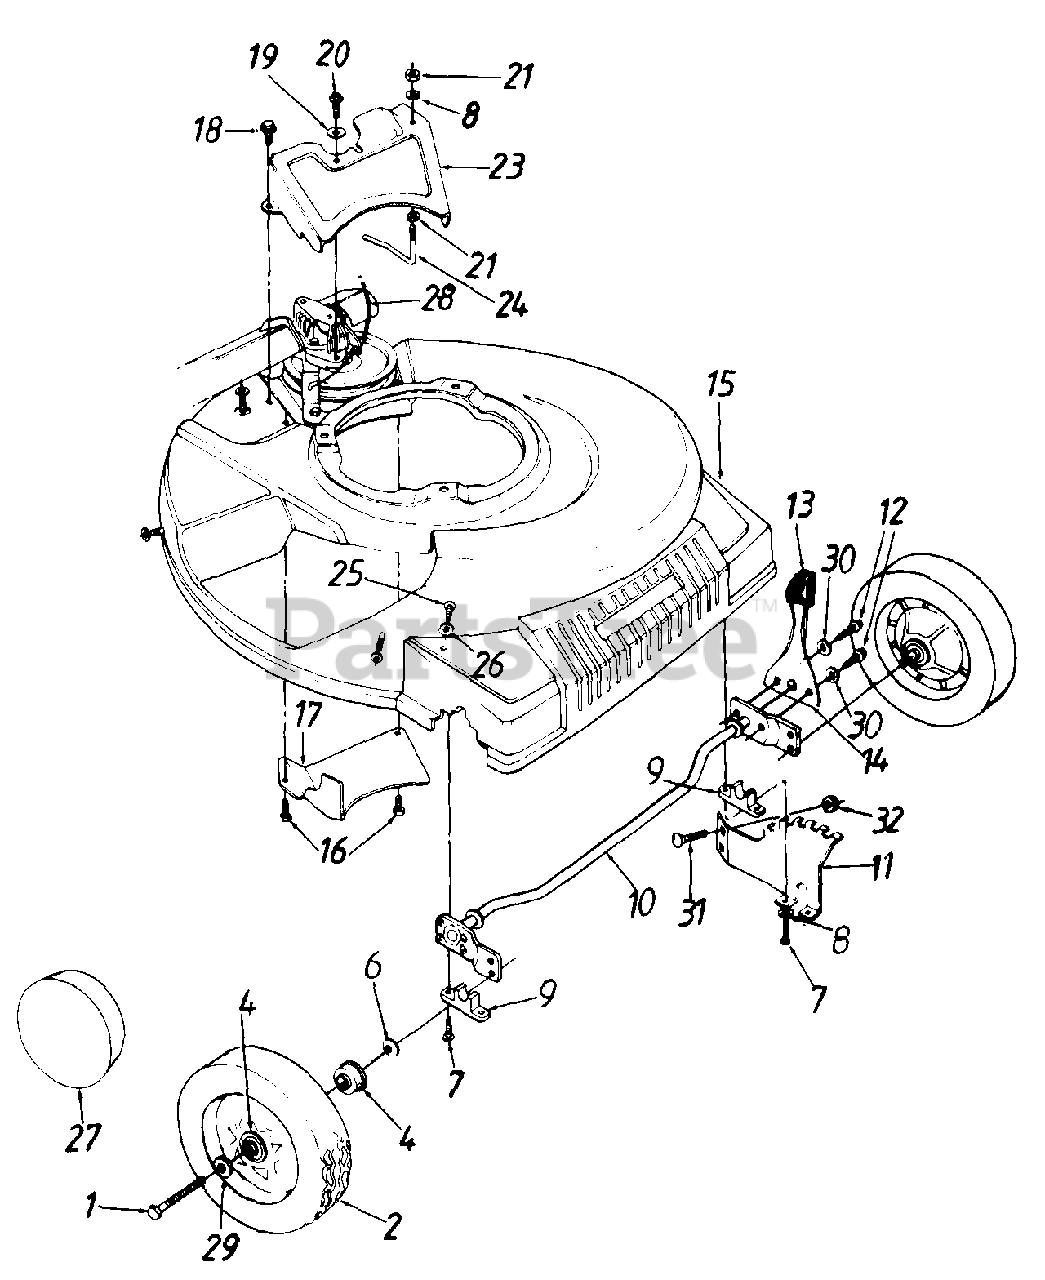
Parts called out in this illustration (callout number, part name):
1	Front Axle Bolt
2	Wheel Ass'y, Comp. (Gray)
4	Flange Ball Brg. .501" I.D.
6	Bell-Wash. .380" I.D. x .88
7	Hex Wash. Hd. Scr. 1/4-20 x 1" Lg.
8	L-Wash. 1/4" I.D.
9	Block Bushing
12	Hex Wash. Hd. TT-Tap Scr. 1/4-20 x .38" Lg.
13	Knob
14	Spring Lever
15	Plastic Front End (Gray)
16	Hex B-Tap Scr. 1/4" x .38"
19	Bell-Wash. .265" I.D. x .75"
20	Hex Wash. Hd. B-Tap Scr. 1/4 x .62" (Spec.)
21	Hex Nut 1/4-20 Thd.
25	Torx Truss Md. Scr. 5/16 x .75"
26	Bell-Wash. .345" I.D. x .88" O.D.
27	Hub Cap (Gray)
28	S.P. Cable 50" Lg.
29	Wave Wash. .51" I.D. x .75" O.D.
30	External L-Wash. 1/4" I.D.
31	Carr. Bolt 1/4-20 x .5" Lg.
32	Hex L-Nut 1/4-20 Thd.
